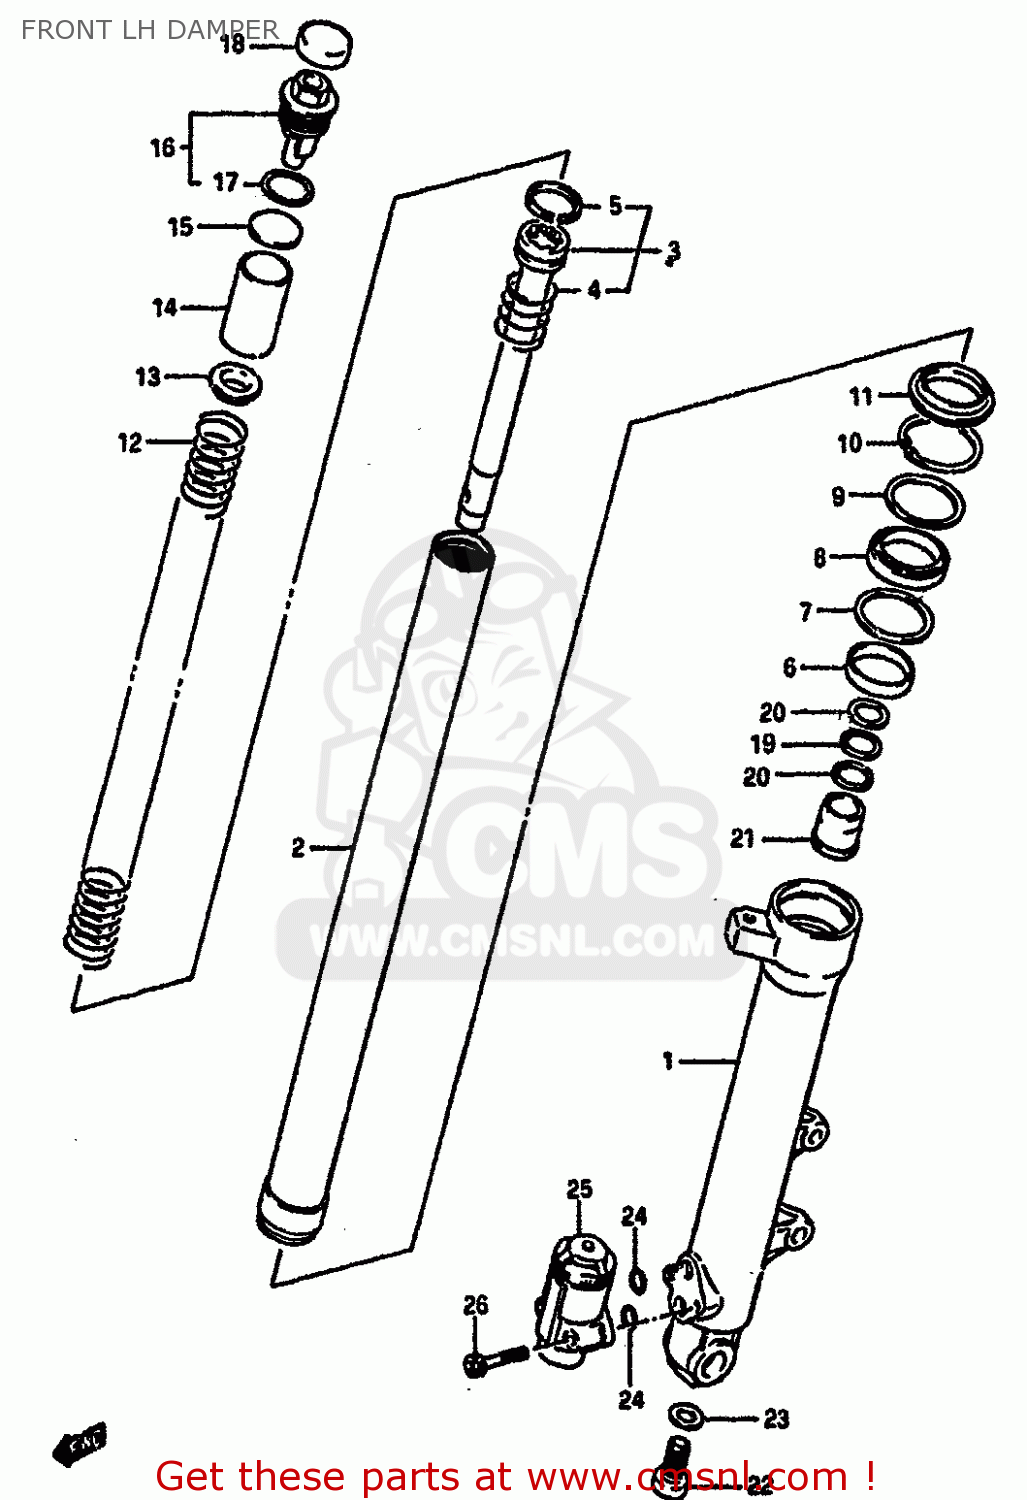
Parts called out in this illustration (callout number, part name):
1	TUBE,OUTER,LEFT
2	TUBE,FORK INNER
3	CYLINDER,FRONT FORK
4	SPRING,FORK REBOUND
5	RING,FR FORK PISTON
6	METAL,SLIDE
7	WASHER,FORK OIL SEAL
8	OIL SEAL,FRONT FORK
9	WASHER,FORK OIL SEAL
10	RING,OIL SEAL STOPPER
11	DUST SEAL,FRONT FORK
12	SPRING,FRONT FORK
13	WASHER
14	SPACER
15	WASHER,FR FORK SPRING
16	CAP,FORK INNER TUBE
17	O RING
18	CAP,FORK INNER TUBE
19	WASHER,OIL LOCK PIECE
20	SPRING,FORK OIL LOCK PIECE
21	PIECE,OIL LOCK
22	BOLT(14X25)
23	GASKET (NAS)
24	O RING
25	PDF ASSEMBLY
26	BOLT
